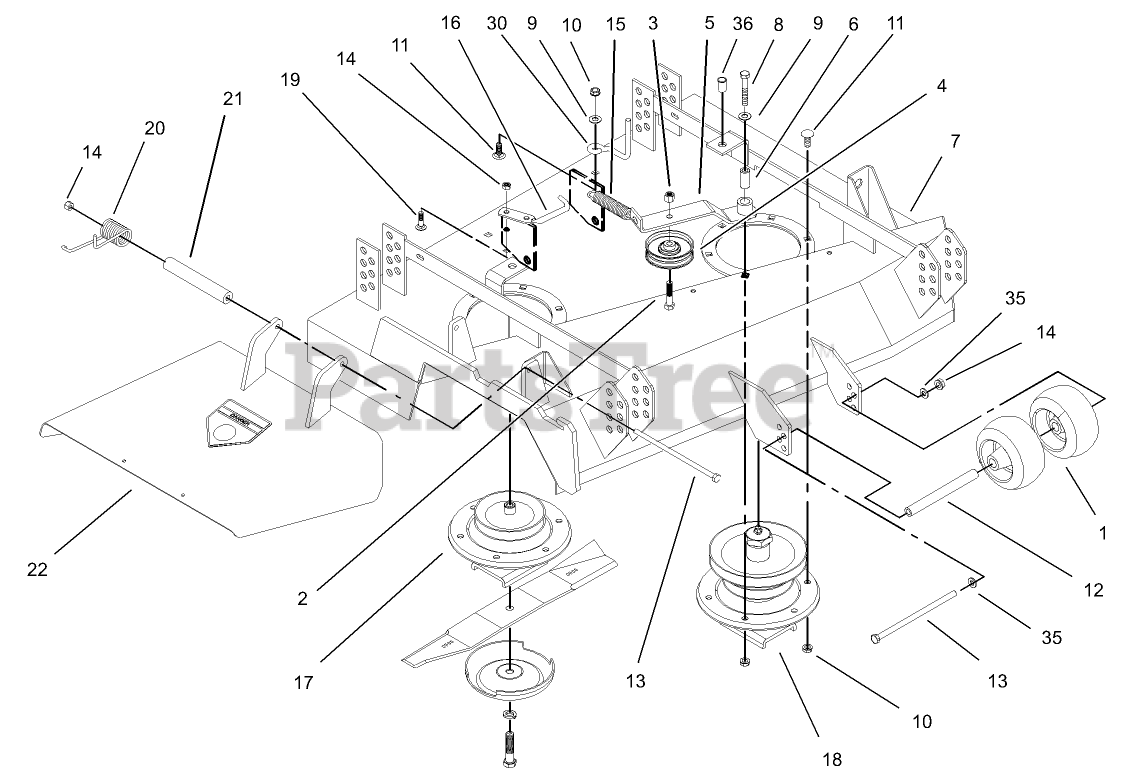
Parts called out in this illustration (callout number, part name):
1	WHEEL-GAGE
2	SCREW-HH
3	NUT-HEX
4	PULLEY-IDLER
5	IDLER ARM ASM
6	SLEEVE-PIVOT, IDLER
7	Deck ASM
8	SCREW-HH
9	WASHER-FLAT
10	NUT-HF
11	SCREW-CARR
12	SPACER-WHEEL
13	SCREW-HH
14	NUT-LOCK, NI
15	SPRING-EXTENSION
16	ROD - SPRING
17	SPINDLE ASM
18	HOUSING - SPINDLE ASM
19	SCREW-CARR
20	SPRING-TORSION
21	SPACER
22	X-REF 105-4623
30	ROD-BELT
35	WASHER-PLAIN
36	INSERT-NUT
